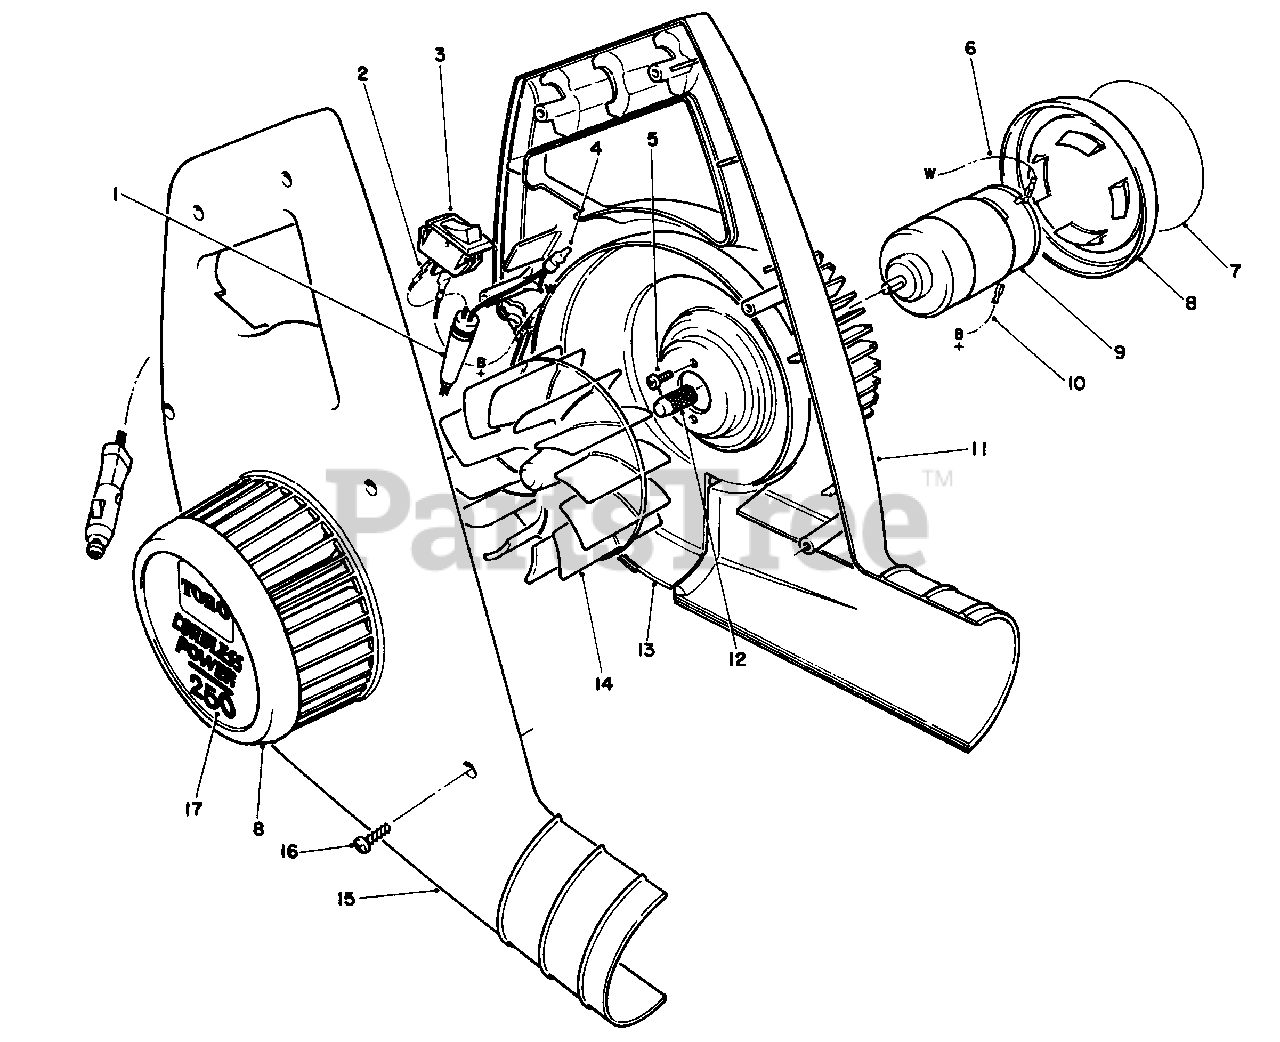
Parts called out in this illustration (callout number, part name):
1	Cord-Power Supply
2	Terminal-Female
4	Connector-Wire
6	Wire Assembly (White)
7	Decal-Warning
8	Cover-Intake
9	Motor-12 Volt
10	Wire Assembly (Black)
11	Housing-L.H.
12	Shaft-Knurled
13	Cover-Motor
14	Impeller
15	Housing-R.H.
16	Screw-Thread Forming
17	Decal-Toro
